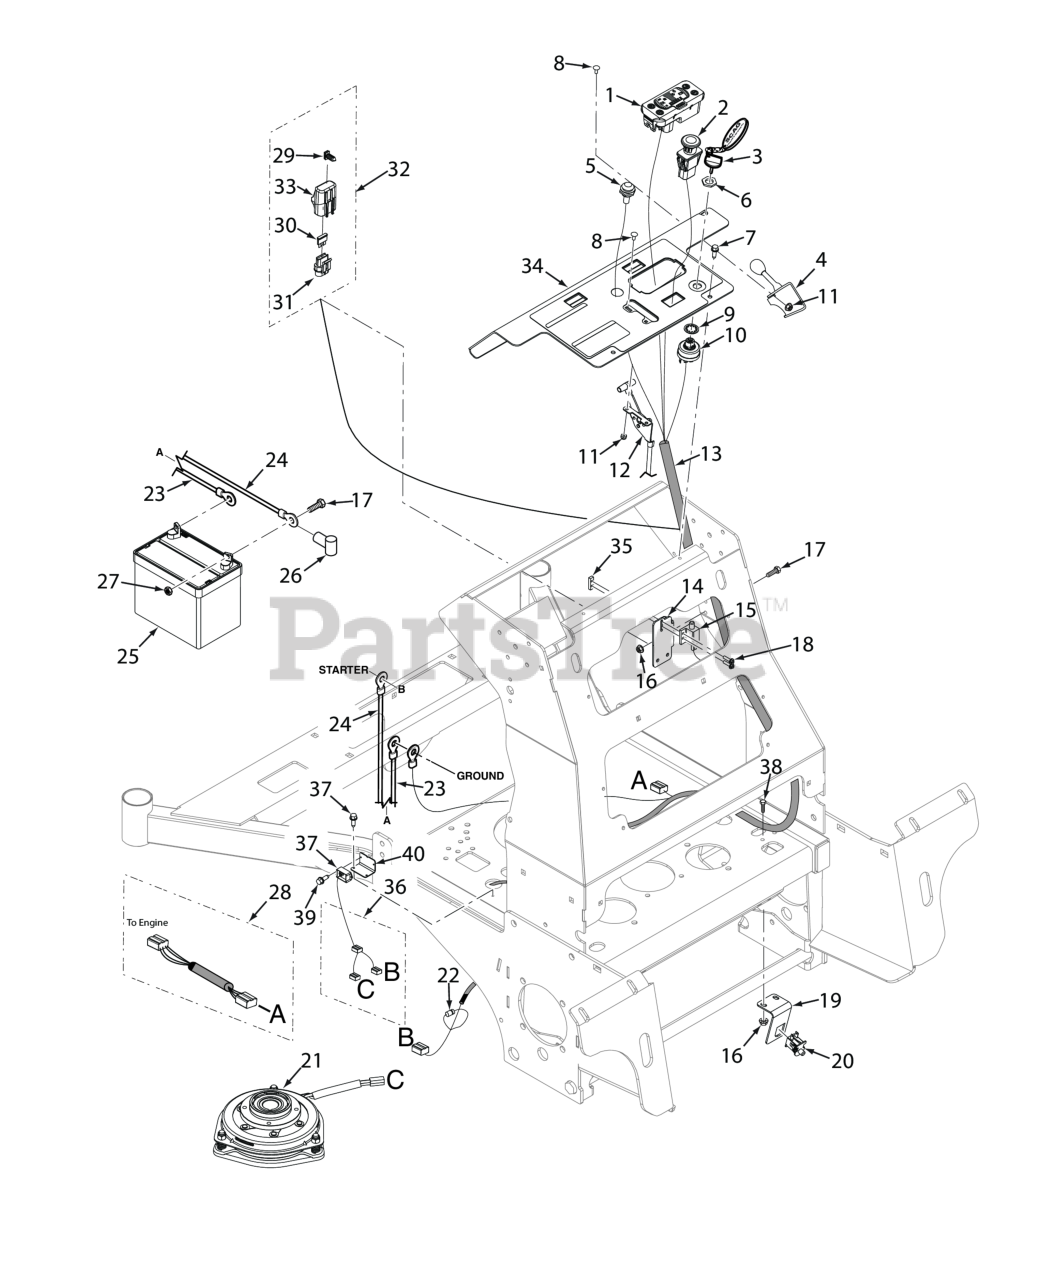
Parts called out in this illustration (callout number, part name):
1	Tiger Eye, Cluster Gauge
2	Switch, PTO - 10 Amp
3	Key, Assembly w/Fob
4	Control Cable, Air Direction
4	Knob, Throttle
5	Indicator Light, Glow Plugs (Includes Mounting Hardware)
6	Nut, 5/8-32 Special
7	Screw, Self-Tapping 1/4-20 x 3/4
8	Bolt, Carriage #10-24 x 1/2"
9	LOCK WASHER, 5/8" INTERNAL TOOTH
10	KEY SWITCH(INCLUDES MOUNTING HARDWARE)
11	Nut, Elastic Stop #10-24
12	Throttle Control, SVR
13	Wire Harness, SVRII-EFI
14	Bracket, Neutral Switch
15	Switch, Interlock, Park Brake Normally Open
16	NUT, 1/4-20 SERRATED FLANGE HEX HEAD
17	BOLT, HEX HEAD, 1/4-20 X 3/4 GR.5
18	Screw, Hex-Slotted Washer Head #10 32 x 3/4"
19	Mounting Bracket, Footplate Switch
20	SWITCH, NEUTRAL INTERLOCK
21	Clutch, GT3.5 (28.6mm Bore)
22	Diode, 600V 6 Amp
23	Battery Cable, 39" Black (26EFI) - Kohler
24	Battery Cable, 44" Red w/Braid (26EFI) - Kohler
25	Battery, 350 CCA (not available through Scag)
26	RUBBER BOOT
27	Nut, 1/4 - 20 Hex
28	Wire Harness Adapter, Briggs & Stratton 37 BV-EFI
29	Clip, Fuse Holder
30	FUSE, 20 AMP BLADE TYPE AUTOMOTIVE
31	Fuse Holder Assembly
32	Single Fuse Assy., Excluding Fuse
33	Cover, Sealed Single
34	Control Panel w/Decals
35	Plate, Threaded
36	Wire Harness, Clutch Soft Start
37	Soft Start Module, Clutch
38	Serr. Fl. Hex Head CPSCR, 1/4-20 x 3/4"
39	Screw, #10-32 x .563 Shakeproof
40	Mounting Bracket, Soft Start Module
